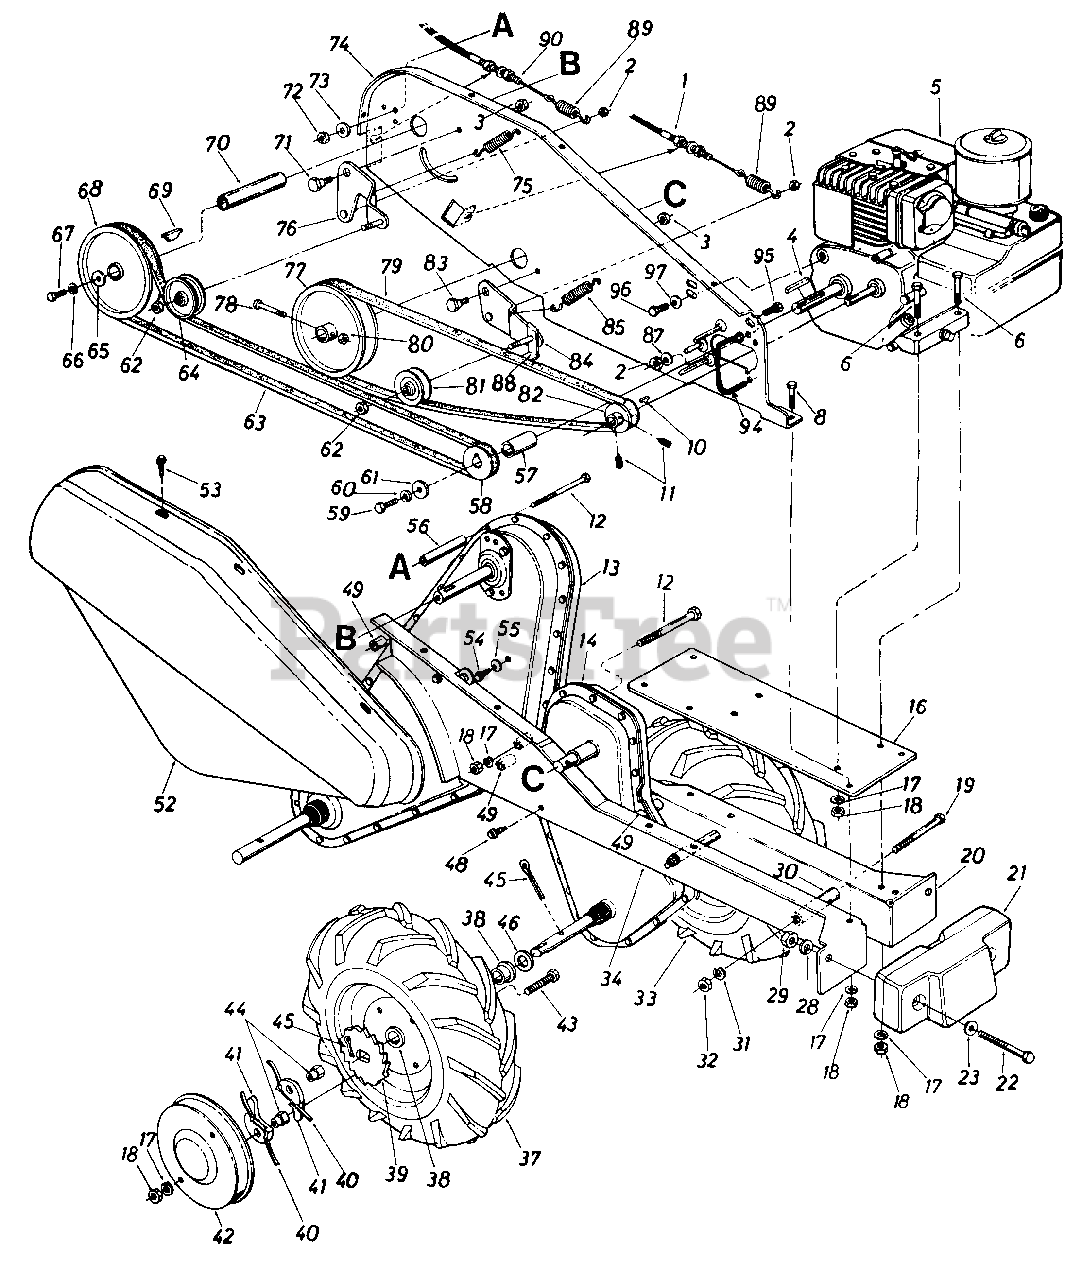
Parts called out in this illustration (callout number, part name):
1	Clutch Control Cable
2	Hex Cent. L-Nut 1/4-20 Thd.
3	Hex Cent. L-Nut 3/8-16 Thd.
4	Sq. Key 3/16" Dia. x .75
5	Eng i ne
6	Hex Bolt 5/16-18 x 1.50" Lg.
8	Hex Bolt 5/16-18 x .75" Lg.
10	Hi-Pro Key #5 Woodruff
11	Set Scr. 1/4-28 x .25" Lg.
12	Hex Bolt 5/16-18 x 3.0" Lg.
18	Hex Nut 5/16-18 Thd.*
19	Hex Bolt 3/8-24 x 3.0" Lg.
22	Hex Bolt 1/2-13 x 4.0" Lg.
23	Fl-Wash. 1/2" I.D. x 1.0" O.D.
28	L-Wash 1/2" I.D.
29	Hex Nut 1/2-13 Thd.
30	Spacer 3/8" I.D. x 5/8" O.D. x 2.18" Lg.
31	L-Wash. 3/8" I.D.
32	Hex Nut 3/8-24 Thd.
33	Comp. Wheel Ass'y.-L.H.
38	Flange Brg. 7/8" I.D. x 1.12" Lg.
39	Ratchet Wheel
40	Nylon Spring
41	Pawl .44" I.D.
42	Wheel Cover
43	Hex Nut 5/16-18 x 1.25" Lg.
44	Special Hex Nut 5/16-24 Thd.
45	Cotter Pin 1/8" Dia. x 1.25" Lg.*
46	Fl-Wash. 7/8" I.D. x 1-3/8" O.D. x .06
48	Hex Wash. Self-Tap Scr. 5/16-24 x .50" Lg.
49	Spacer 5/16" I.D. x 16 Ga. x.96" Lg.
52	Belt Cover
53	Hex Wash. S-Tap Scr. 1/4-20 x.50" Lg.
54	Hex Wash. S-Tap Scr. 1/4-20 x 3/8" Lg.
55	Bell-Wash. 1/4" I.D.
56	Spacer 3/8" I.D. x 1/2" O.D. x2.0" Lg.
57	Spacer 3/4" I.D. x 1.12" O.D. x 1.56" Lg.
58	1/2" "V"-4L Pulley 314" I.D. x 2.59 " O.D.
59	Hex Bolt 3/8-24 x 1.00" Lg.
60	L-Wash. 3/8" I.D.
61	Fl-Wash. 3/8" I.D. x 1.25" O.D.
62	Hex L-Nut 3/8-24 Thd.
63	'V"-Belt 1/2" X 54" Lg.
64	Fl-ldler Pulley 3.75" O.D. x 3/8" I.D.
65	Fl-Wash. .25" I.D. x .93" O.D. x .1 20
66	L-Wash. 1/4" I.D.
67	Hex Bolt 1/4-28 x .75" Lg.
68	Split Pulley 6" Dia. x 5/8" I . D.
69	Hi-Pro Key
71	Shld. Bolt 1/2" Dia. x .210" Lg.
72	Hex Nut 5/16-18 Thd.
73	L-Wash. 5/16" I.D.
74	Side Plate Ass'y.
75	Ext. Spring .50" O.D. x 1.55" Lg.
76	Idler Bracket Ass'y.-Tines
77	Pulley 6" Dia. x 5/8" I.D.
78	Hex Bolt 1/4-28 x 1.50" Lg.
79	"V"-Belt 1/2" X 42" Lg.
80	Hex Cent. L-Nut 1/4-28 Thd.
81	"V"-ldler Pulley 2-5/8" O.D.
82	1/2" "V"-Pulley 2-1/4" O.D. x .50" I.D.
83	Shld. Bolt 1/2" Dia. x .160" Lg.
84	Idler Bracket Ass'y-Whee I s
85	Ext. Spring .50" O.D. x 1.97" Lg.
87	Bell-Wash. 1/4" I.D.
88	Belt Keeper Ass'y.
90	Clutch Control Cable
94	Belt Keeper
95	Hex Bolt 1/4-20 x 1.25" Lg.
96	Hex Bolt 5/16-24 x .62" Lg.
97	Bell-Wash. 5/16" I.D.
